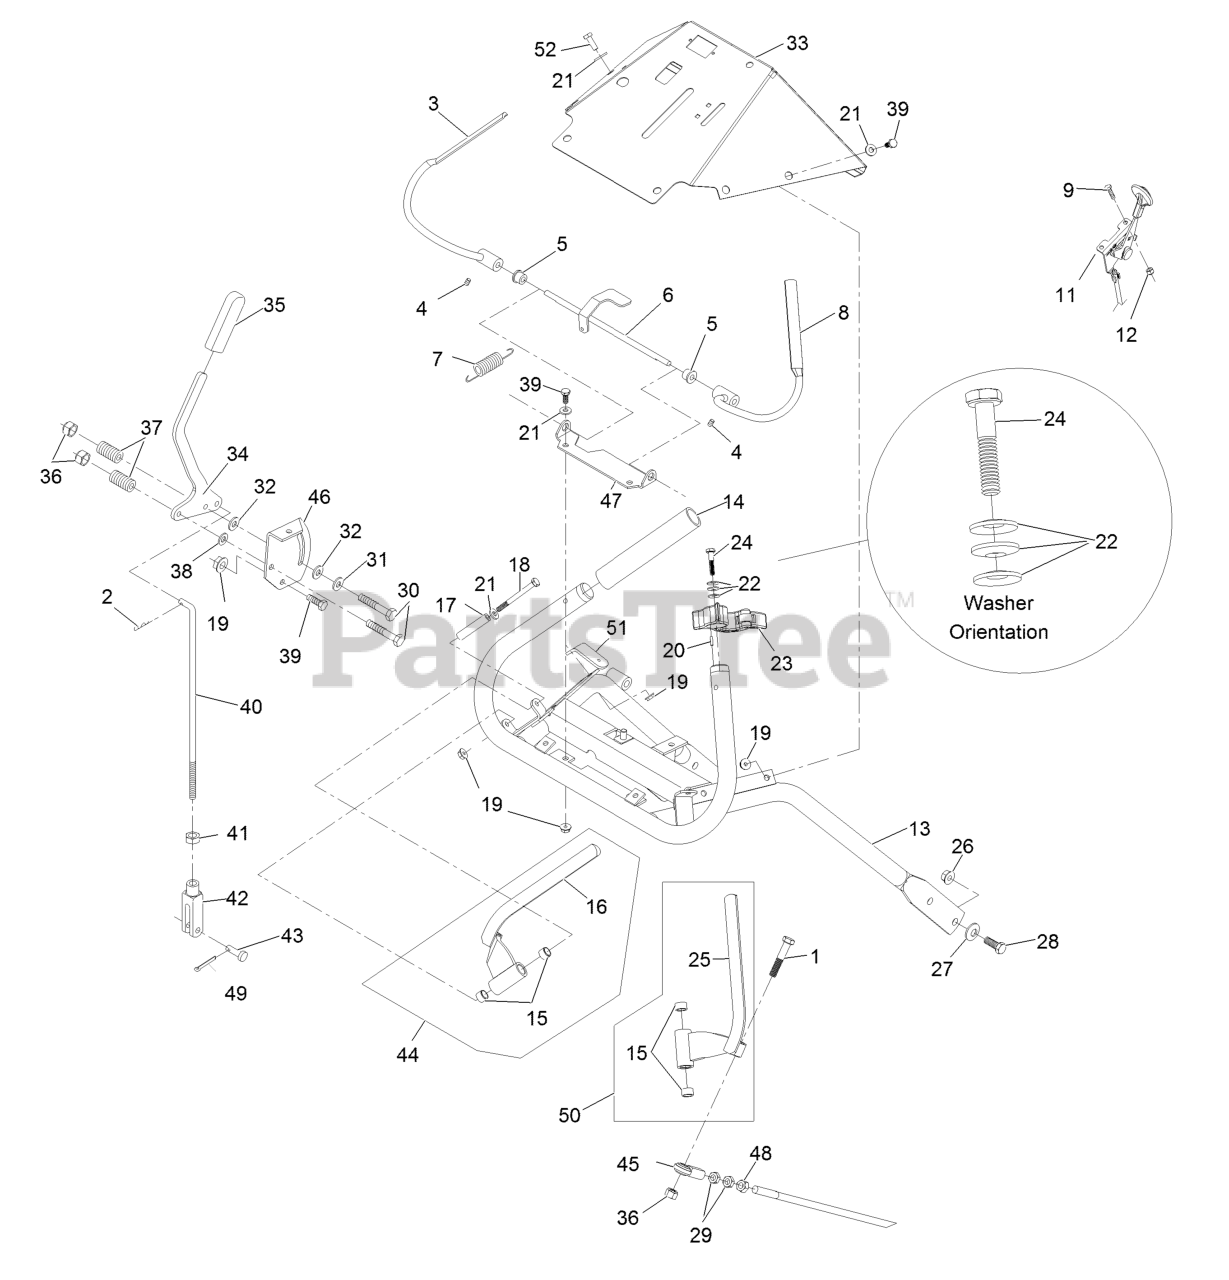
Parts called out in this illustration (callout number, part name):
1	SCREW-HH
2	PIN-COTTER
3	WLD,LH OPC LEVER
4	SCREW-SET
5	BUSHING-NYLON
6	WLD,OPC LEVER AXLE
7	SPRING-EXTENSION
8	WLD,RH OPC LEVER
9	BOLT-CARR
11	CONTROL-THROTTLE
12	NUT-LOCK, NI
13	WLD,TTH ECS HANDLE
14	GRIP-BAR, HANDLE
15	BUSHING-SLEEVE
16	WLD,LH DRIVE LEVER
17	BUSHING-LEVER, DRIVE
18	SCREW-HH
21	WASHER-FLAT
22	WASHER-SPRING
23	ASM,LATCH RH THUMB
24	SCREW-HH
25	WLD,RH DRIVE LEVER
26	NUT-HHF, WHIZ
27	WASHER-BELLEVILLE
28	SCREW-HH
29	NUT-HJ
30	SCREW-HH
31	WASHER-FRICTION
32	WASHER-FRICTION
33	ASM, CONSOLE WITH DECALS
34	LEVER, SHIFT W/GRIP
35	GRIP-HANDLE, STEERING
36	NUT-LOCK, NI
37	SPRING-COMPRESSION
38	WASHER-PLAIN
39	SCREW-HH
40	ROD,SPEED CONTROL
41	NUT-JAM
42	YOKE-ADJUSTABLE
43	PIN-CLEVIS
44	DRIVE LEVER-ASM, LH
45	JOINT-BALL, END
46	BRACKET,SHIFTER SLIDE (PL
47	BRACKET,OPC AXLE
48	NUT-HEX
49	PIN-COTTER
50	DRIVE LEVER-ASM, RH
51	BRACKET-RELAY
52	SCREW-HH
